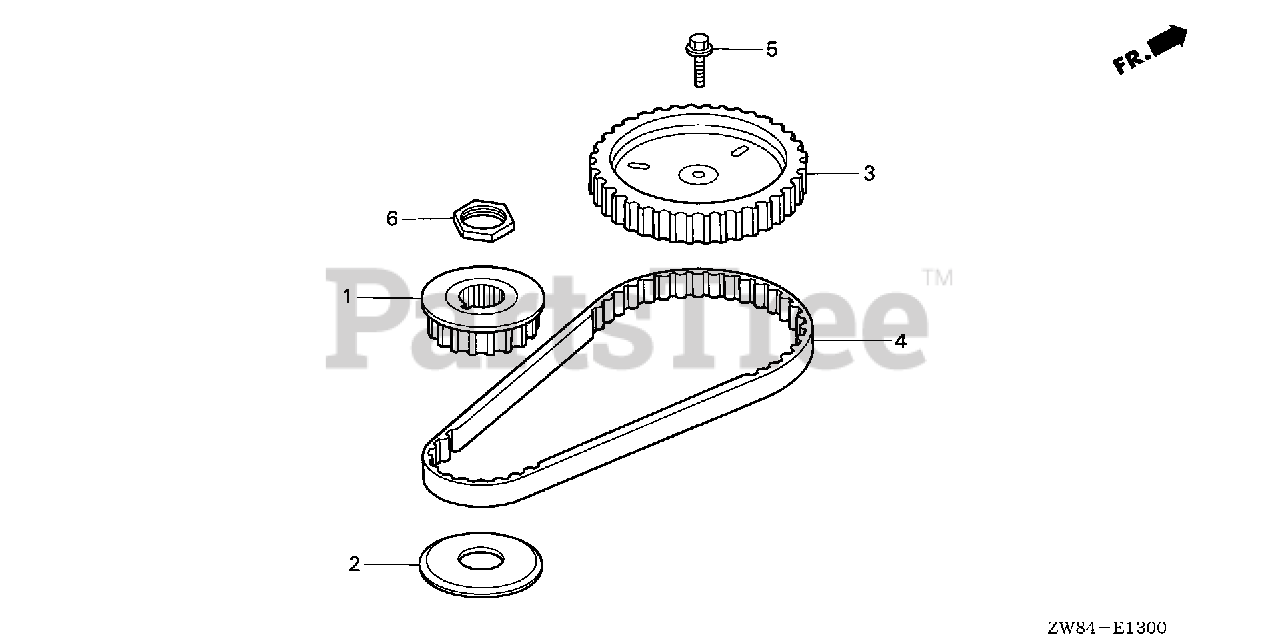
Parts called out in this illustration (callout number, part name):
1	PULLEY, TIMING
2	FLANGE, TIMING PULLEY
3	PULLEY, CAMSHAFT
4	BELT, TIMING (63RU13 B-333)
5	BOLT, FLANGE (6X20)
6	NUT, LOCK (24MM)
